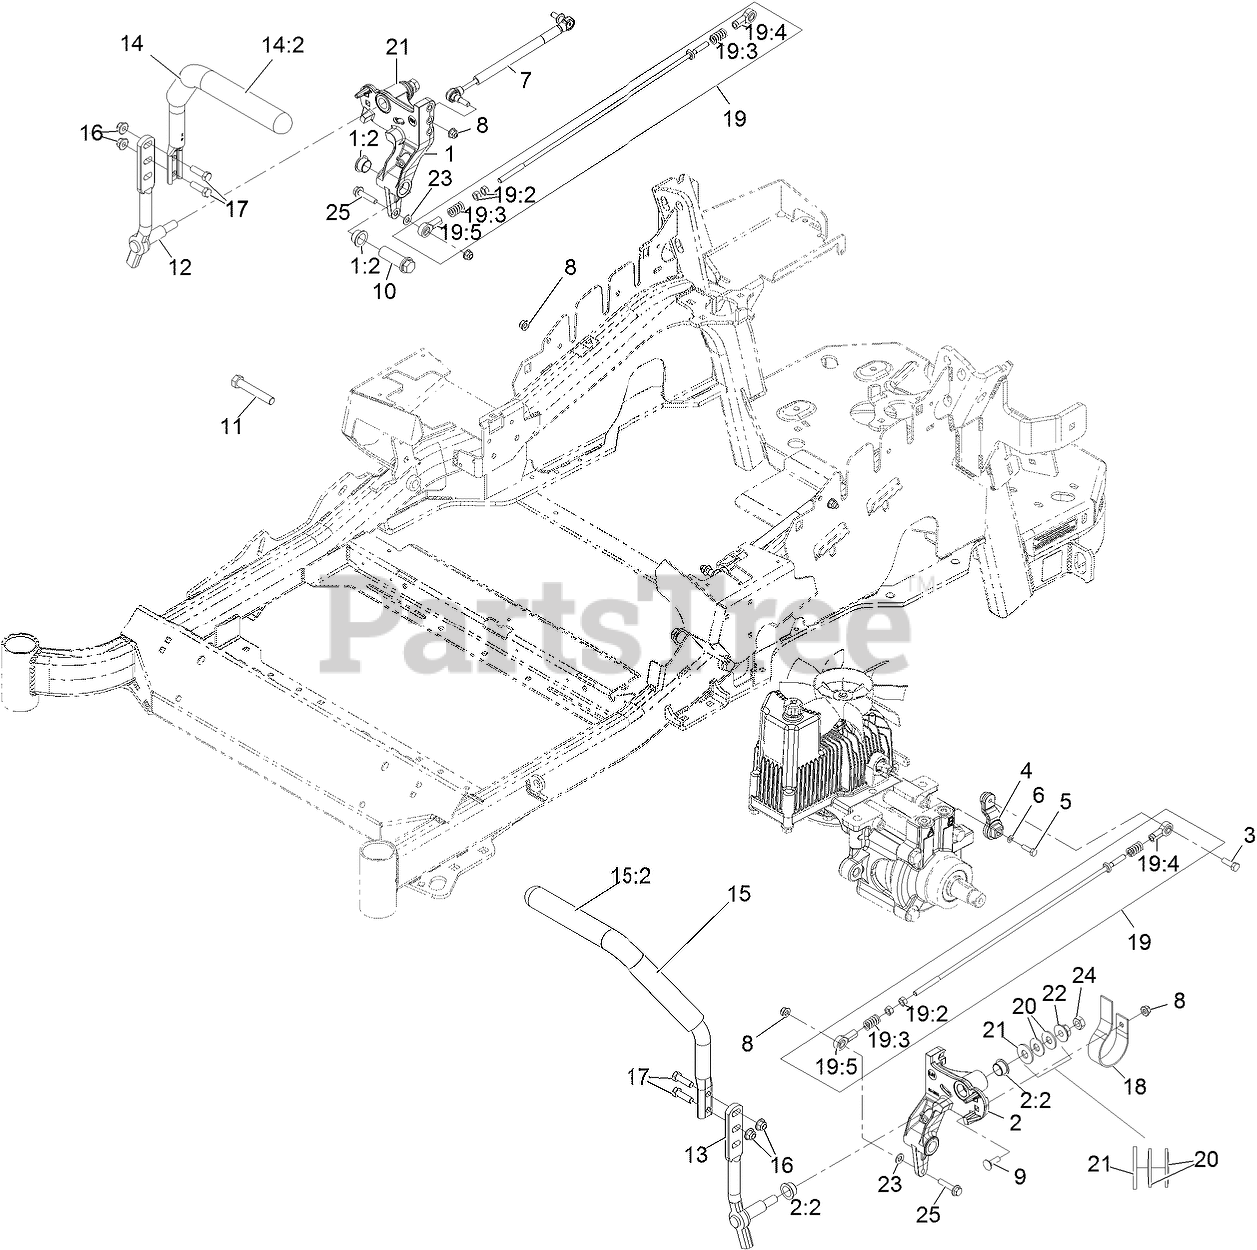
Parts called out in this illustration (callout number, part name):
1	RH MOTION CONTROL AND BUSHING ASM
1:2	BUSHING-FLANGE
2	LH MOTION CONTROL AND BUSHING ASM
2:2	BUSHING-FLANGE
3	SCREW-HH, THREAD LOCKING
4	ARM-CONTROL, PUMP
5	SCREW-HH
6	WASHER-SPRING
7	DAMPER-CONTROL, MOTION
8	NUT-HF, NI
9	BOLT-CARR
10	HUB-THREADED
11	SCREW-HH
12	LEVER-CONTROL MOTION, RH
13	LEVER-CONTROL MOTION, LH
14	RH HANDLE ASM
14:2	GRIP-LEVER, CONTROL
15	LH HANDLE ASM
15:2	GRIP-LEVER, CONTROL
16	NUT-HF, NI
17	SCREW-HH
18	SPRING-LEAF
19	PUMP LINKAGE REAR ASM
19:2	NUT-HEX
19:3	SPRING-COMPRESSION
19:4	BALLJOINT-LH
19:5	BALLJOINT-RH
20	WASHER-SPRING
21	WASHER-FLAT
23	WASHER-PLAIN
24	NUT-JAM
25	SCREW-HHF
